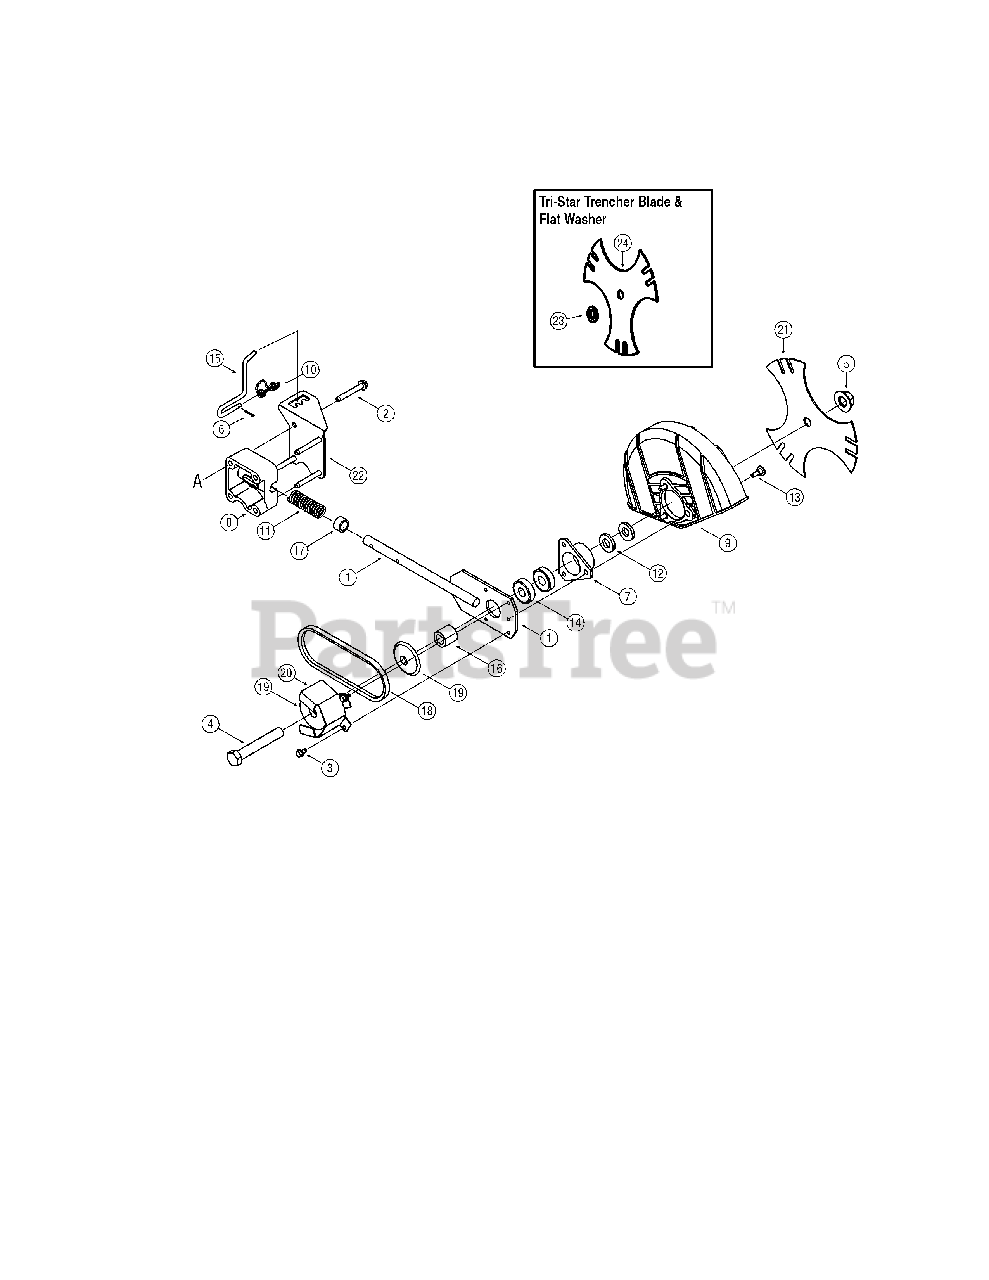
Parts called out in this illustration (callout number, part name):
1	Blade Plate Assembly
2	Hex Screw, 5/16-18
3	Self-tapping Screw, 1/4-20
4	Hex Screw, 5/8-18
5	Flange Nut, 5/8-18
6	Clevis Pin 3/32 x .625
7	Bearing Cup
8	Bearing Block
9	Blade Guard
10	Double Torsion Spring
11	Compression Spring
12	Flat Washer .635x1.24x.
13	Shoulder Screw
14	Bearing, .625 ID x 1.57
15	Blade Adjustment Rod
16	Spacer, .63 x 1.12 x 1
17	Spacer, .64 x.88 x .50
18	Belt
19	Sheave
23	Flat Washer
